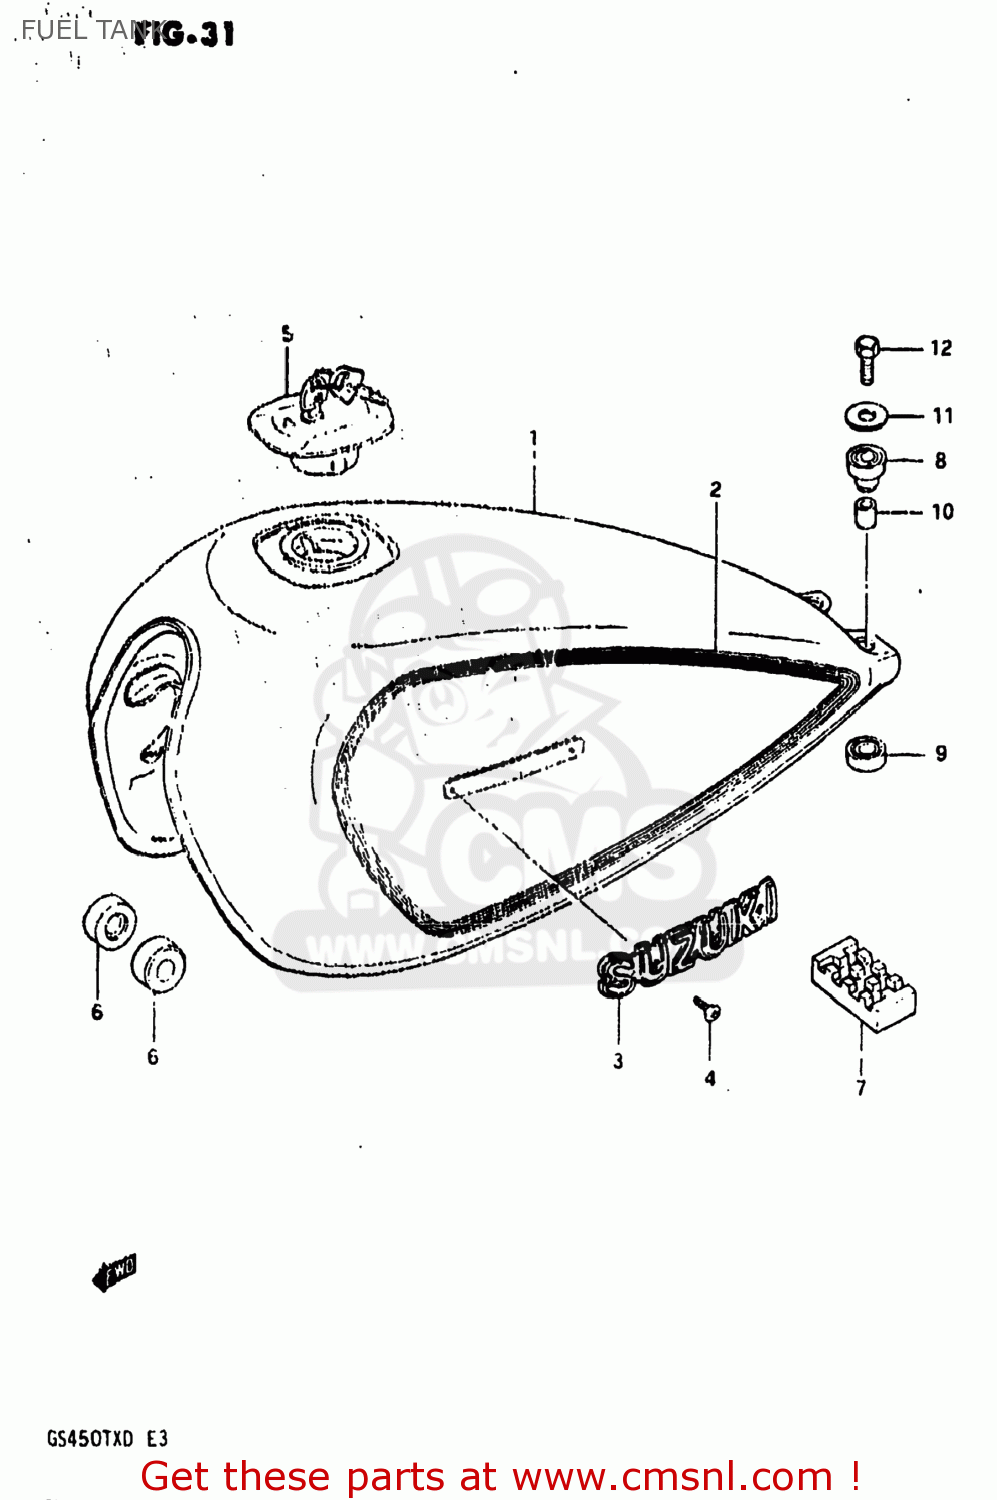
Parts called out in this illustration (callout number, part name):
1	TANK ASSEMBLY,FUEL
2	TAPE SET,FUEL TANK
3	EMBLEM,FUEL TANK
4	SCREW 3X6
5	CAP SET,FUEL TANK
6	CUSHION
7	CUSHION
8	CUSHION
9	CUSHION
10	SPACER (6.4X9X20)
11	WASHER (6.5X24X1.6)
12	BOLT
